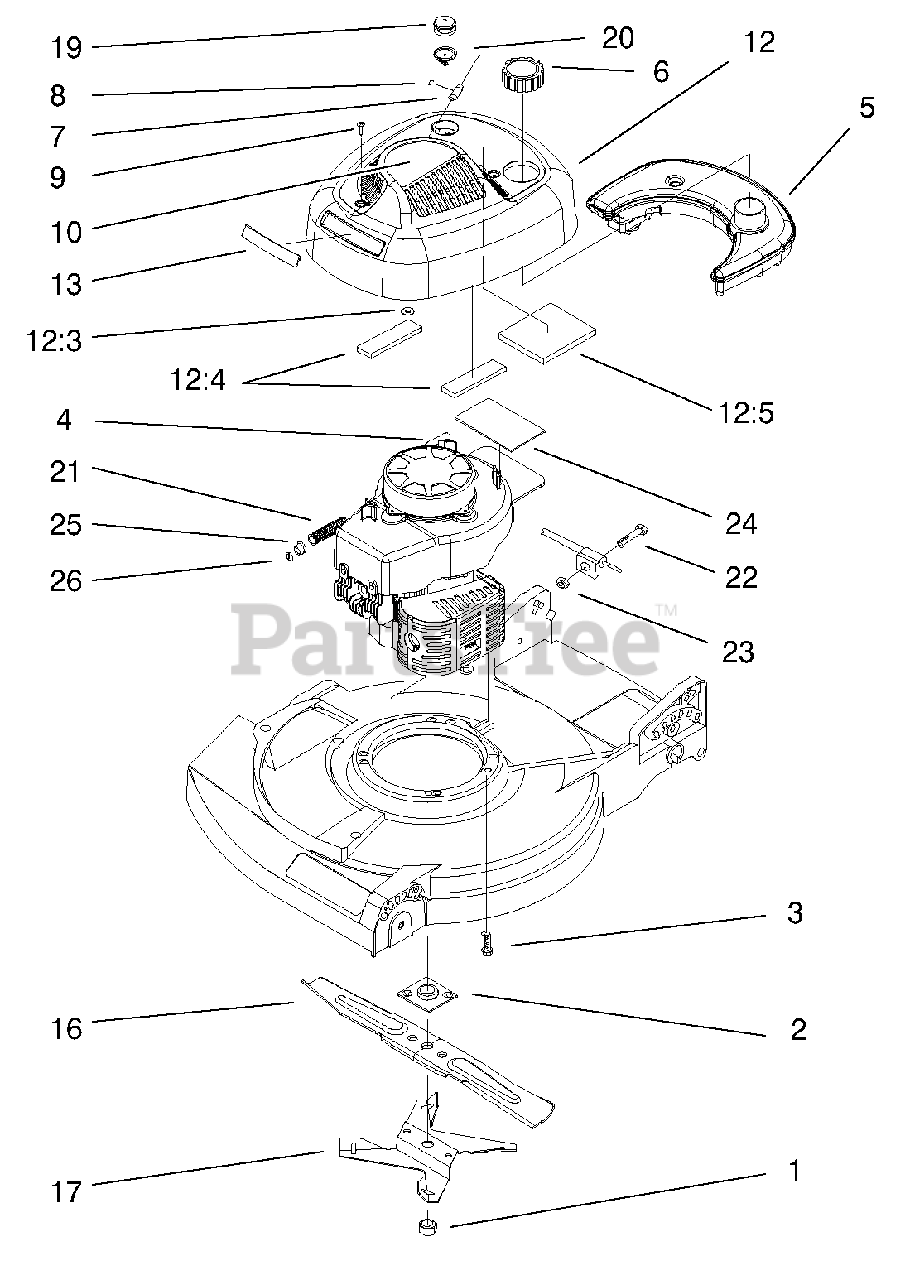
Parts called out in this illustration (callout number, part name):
1	Nut-Blade
2	Plate & Collar ASM
3	Screw-Sems
4	Fuel Line
6	Cap ASM-Fuel & Oil
7	Stop-Rope
8	Staple
9	Screw-Pan Sems
10	Decal-Recoil
12	Shroud-Electric Start
12:3	Push Nut
12:4	Strip-Foam
12:5	Strip-Foam
13	Applique-Shroud
16	Blade
17	Fan-Mulching
19	Bulb-Primer
20	Body-Primer
23	Nut-Hex
24	Pad-Foam
25	Actuator-Brake Lever
26	Retainer
